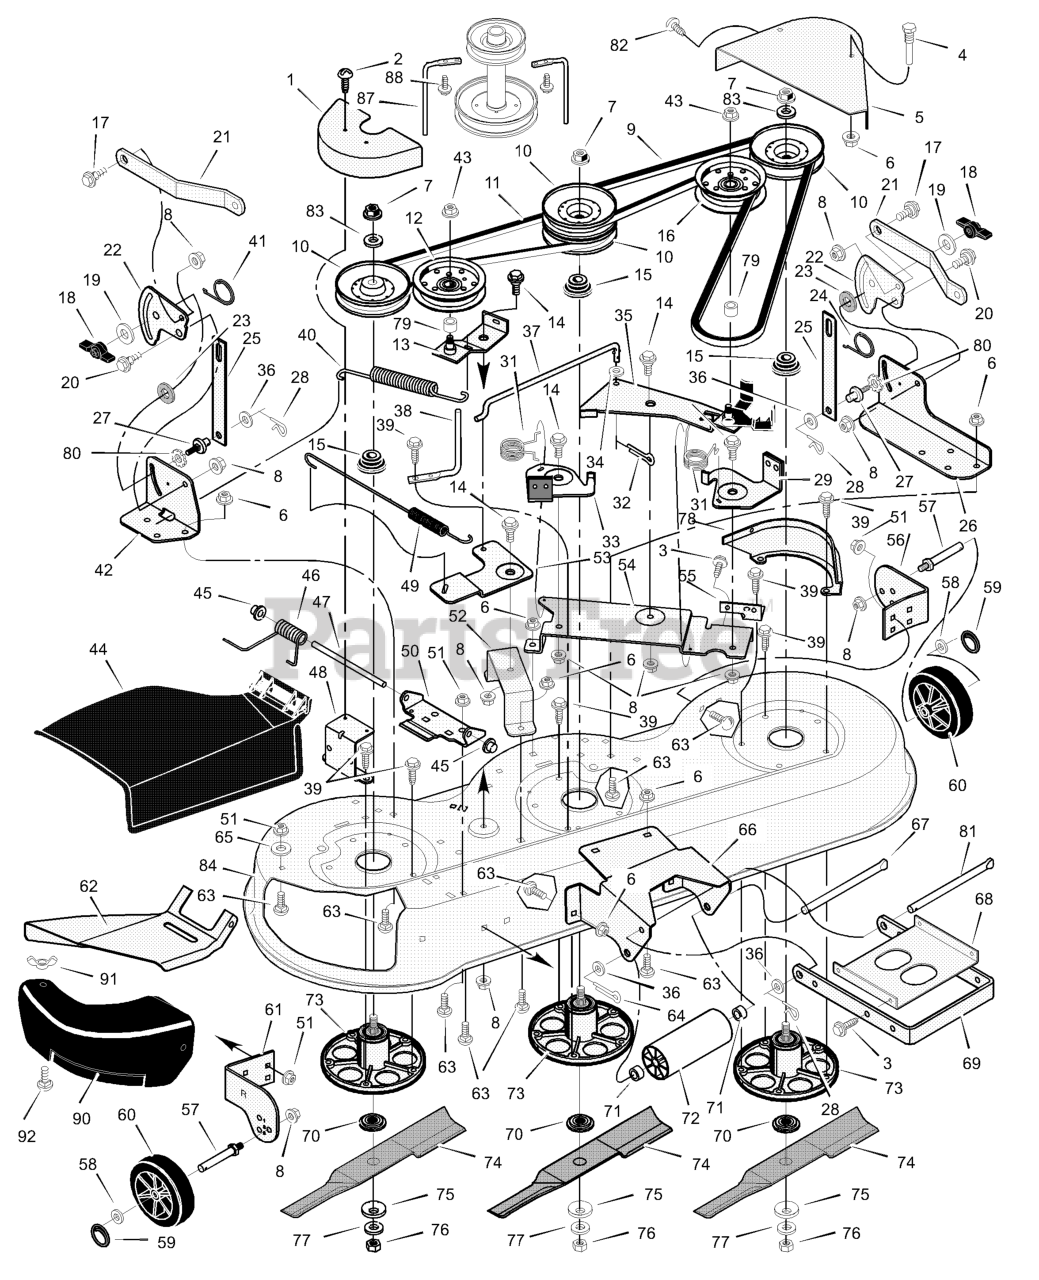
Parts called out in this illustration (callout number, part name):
1	Cover, Right Pulley
2	Screw
4	Guide, Belt
5	Cover, Left Pulley
6	Nut, Hex
7	Nut, Flange
8	Nut, Flange
9	Belt, Primary
10	Pulley
11	Belt, Secondary
12	Pulley, Idler
13	Arm, Idler
14	Bolt, Shoulder
15	Spacer, Pulley
16	Pulley, Idler
17	Bolt, Shoulder
18	Knob
20	Bolt, Shoulder
21	Bracket, Rear Suspension
22	Plate, Suspension
23	Pad, Friction
25	Link, Lift
26	Bracket, Left Lift
27	Pin, Hanger
28	Pin, Hair
29	Brake Assembly, Left
32	Pin, Cotter
33	Brake Assembly, Right
34	Washer
35	Idler, Arm
37	Link, Bell Crank
38	Guide, Belt
39	Screw
40	Spring, Extension
41	Spring, Torsion
42	Bracket, Suspension
43	Nut
44	Deflector, Chute
45	Push On Cap
46	Spring, Torsion
47	Rod, Deflector
48	Bracket, Cover
49	Spring, Extension
50	Bracket, Hinge
51	Nut, Flange
52	Bracket, Bell Crank
53	Crank, Bell
54	Plate, Brake Arm
55	Bracket, Brake Plate
56	Bracket, Left Gauge Wheel
57	BOLT, Gauge Wheel
59	Ring, Locking
60	Wheel, Gauge
61	Bracket, Right Gauge Wheel
62	Deflector, Inside
63	Bolt, Carriage
64	Pin, Cotter
66	Bracket, Front Deck
67	Rod, Hanger
68	Stiffener
69	Bracket, Suspension
70	Adapter, Blade
73	Housing, Jackshaft
75	Washer, Belleville
78	Bracket, Pulley Cover
81	Rod, Hanger
83	Washer
84	Housing, Blade
87	Guide, Belt
88	Screw
90	Cover, Mulch
91	Wingnut
92	Bolt, Carriage
